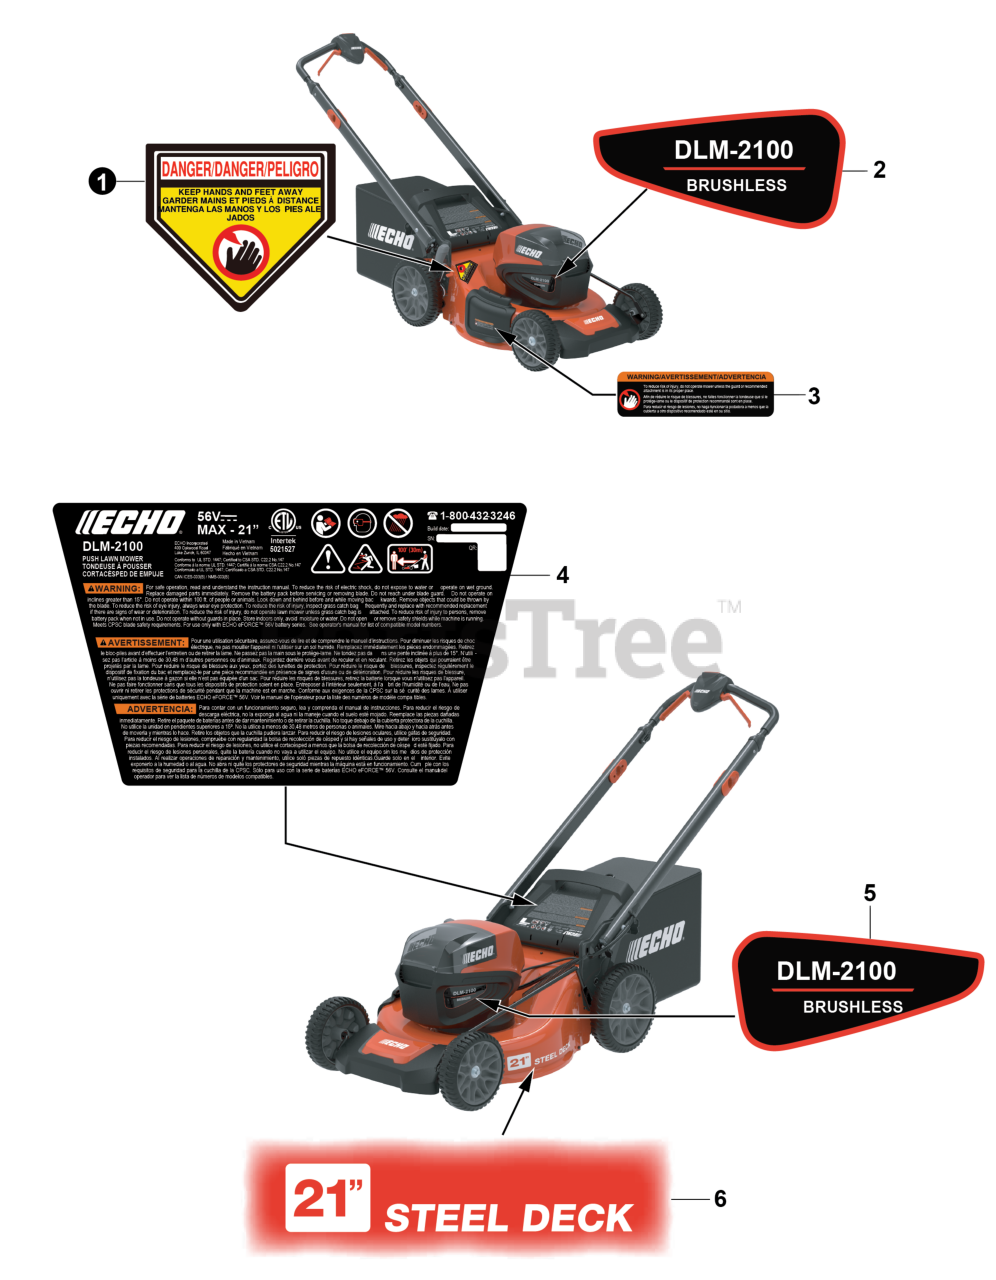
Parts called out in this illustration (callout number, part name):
1	LABEL,WARNING
2	LABEL,RIGHT SIDE MODEL
3	LABEL,SIDE WARNING
4	LABLE,WARNING\SERIAL - VIETNAM
5	LABEL,LEFT SIDE MODEL
6	LOGO,21" STEEL DECK
